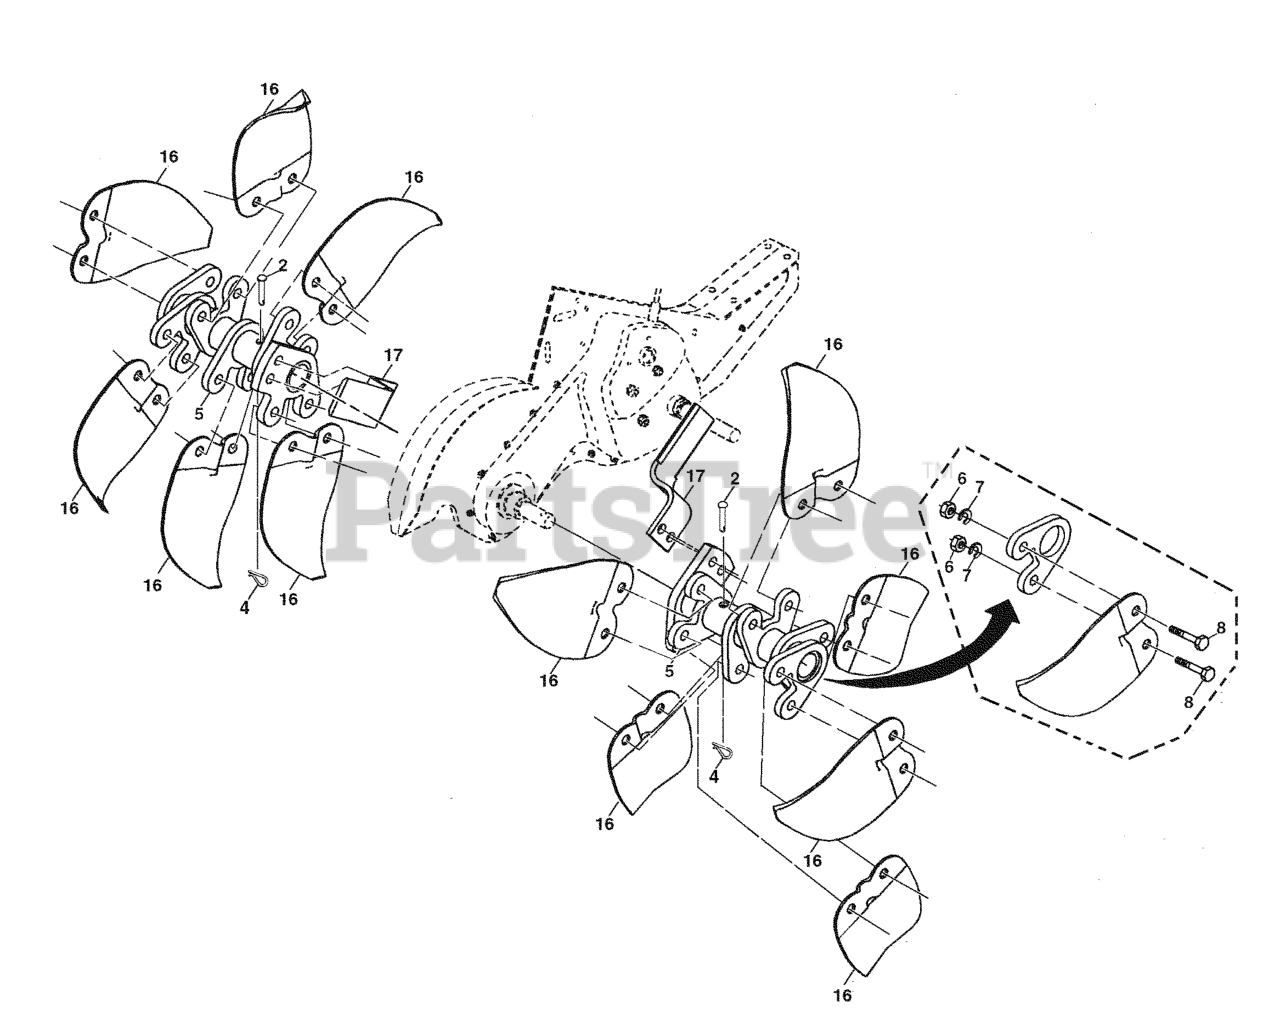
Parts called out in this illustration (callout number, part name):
1	PIN RETAINING SCREW
2	SPRING RETAINER
3	HUB.ASM.DRT17.2004 (CMPL KIT)
4	NUT
5	WASHER, LOCK 3/8
6	BOLT.HEX.001X20.37-24X1.ZINC
7	TINE.SPADE
8	TINE.CLEANING BLACK
